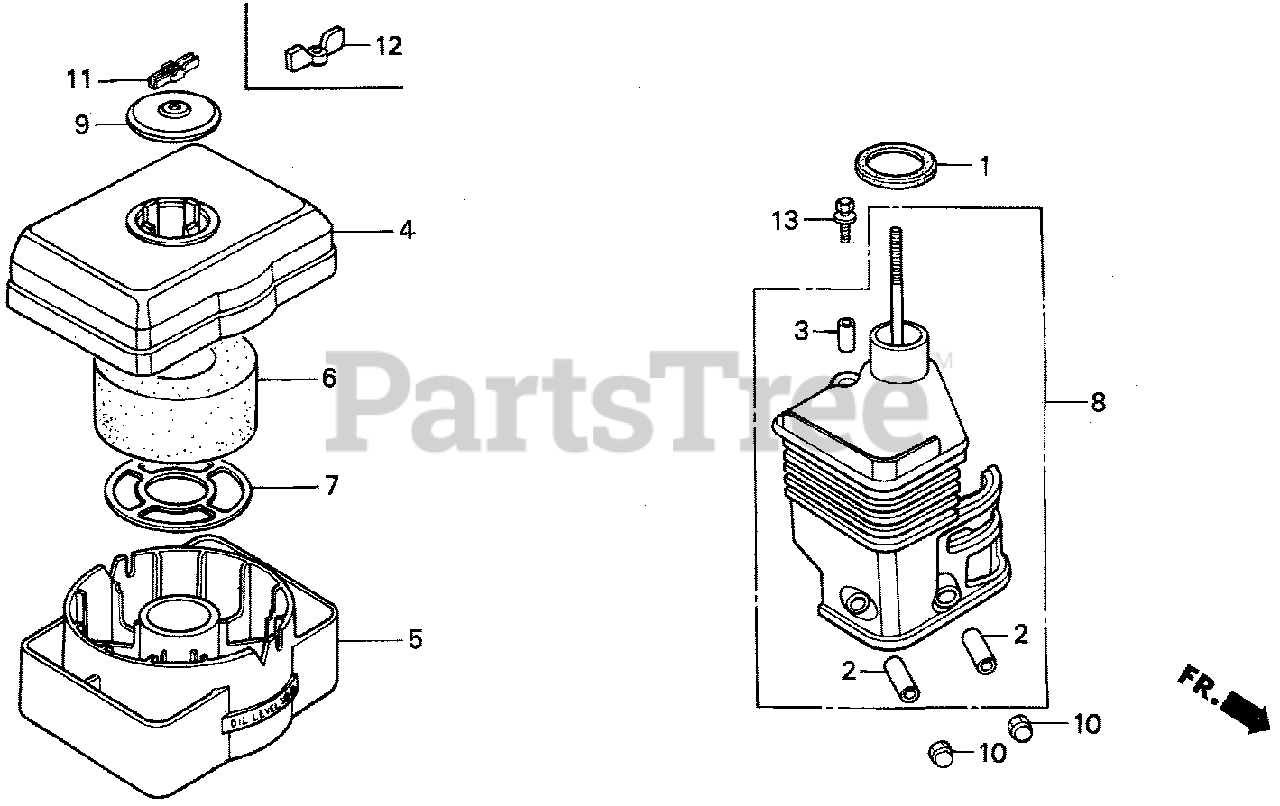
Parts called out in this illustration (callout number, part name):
1	GASKET, ELBOW
2	COLLAR, AIR CLEANER
3	COLLAR B, AIR CLEANER
4	BODY, CLEANER (OIL BATH)
5	PAN, CLEANER OIL (OIL BATH)
6	ELEMENT, AIR CLEANER (OIL BATH)
7	GRID, AIR CLEANER
8	ELBOW, AIR CLEANER
9	CAP, CLEANER
10	NUT, CAP (6MM)
11	WINGNUT (6MM)
12	WINGNUT, TOOL BOX SETTING
13	BOLT-WASHER (6X20)
13	BOLT, FLANGE (6X20)
